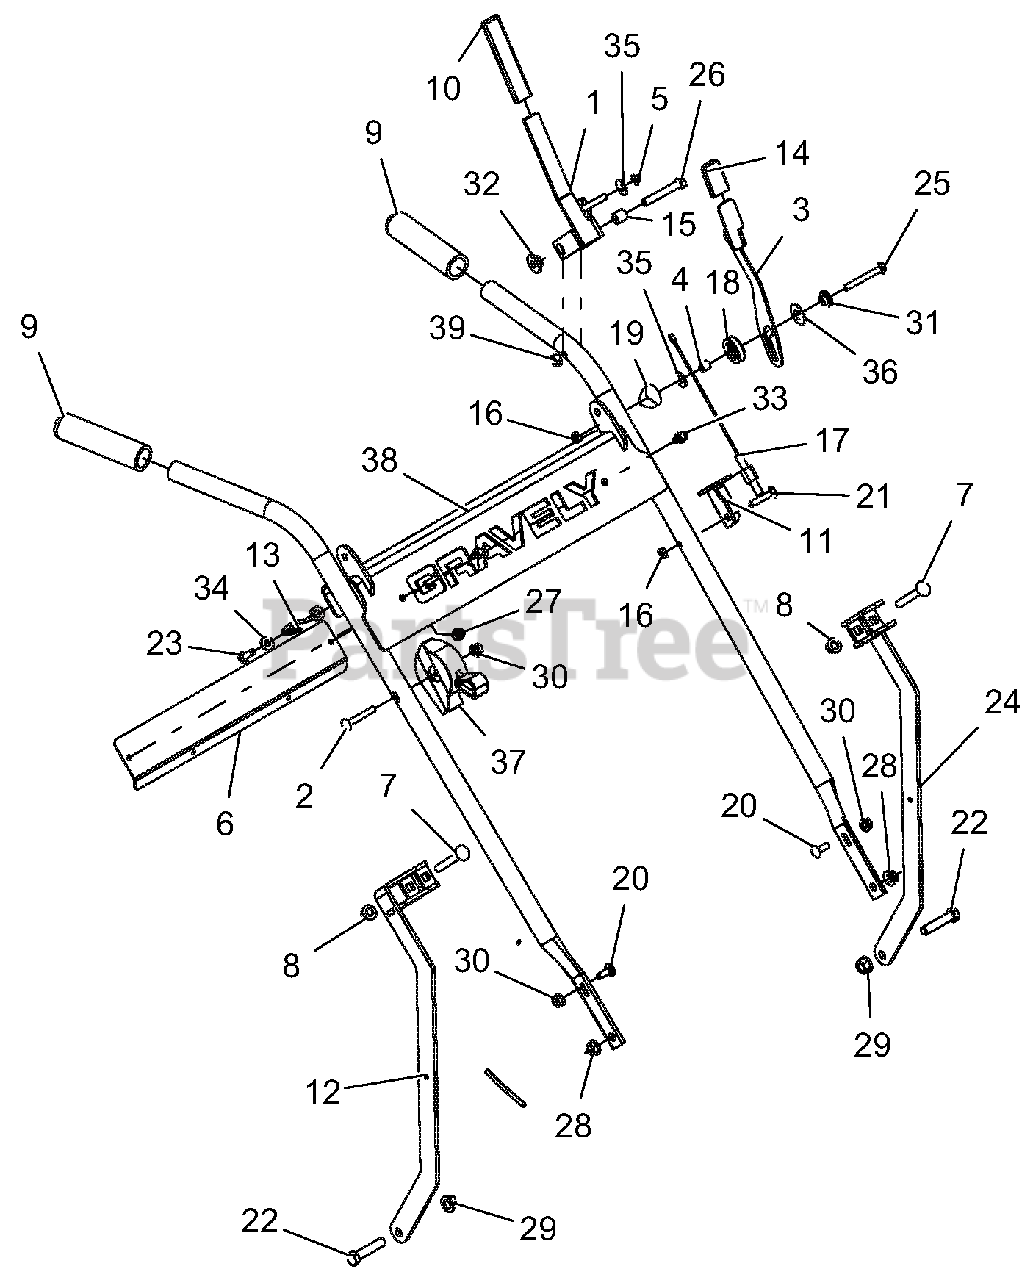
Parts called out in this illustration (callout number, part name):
1	WLDMT, PTO LEVER, HWM (BLACK)
2	BLT-RDHDSQNK .25-20X1.75 G5 Y
3	WLDMT, HWM PTO INTERLOCK
4	TUBE, SPCR .280 X .375 X .375 REV
5	PUSH, NUT .25
6	BACKER, GRAVELY
7	BLT-RDHDSQNK .31-18X2.25 G5 Y
8	NUT-LK-NYL-FLG .31-18 YWZC
9	GRIP, BLACK 7/8ID
10	GRIP, MZR/MOMENT SP 7/8X3/4X4
11	MOUNT, UPPER PTO CABLE (BLACK)
12	WLDMT, RH HANDLEBAR SUPPORT (RED)
13	GUIDE, PULLCORD
14	GRIP, THUMB LATCH
15	BSHG-SLV .334X.500X.50
16	NUT-JAM-NYL .250-20 W/INSERTYZ
17	CABLE, WAW PTO
18	PULLEY, CABLE
19	SPCR, HANDLEBAR
20	BLT-RDHDSQNK .25-20X.75 G5 YWZC
21	BLT-RDHDSQNK .25-20X1.25 G5 Y
22	BLT-HEX .38-16X1.75 GR5 YWZC
23	BLT-HEX .25-20X.75 GR5 YWZC
24	WLDMT, LH HANDLEBAR SUPPORT (RED)
25	BLT-HEX .25-20X2.00 GR5 YWZC
26	BLT-HEX .31-18X2.00 GR5 YWZC
27	NUT-LK-NYL .250-20 YWZC
28	NUT, LK-TOP-FLG .312-18 YWZC
29	NUT, LK-TOP-FLG .38-16 YWZC
30	NUT, LK-TOP-FLG .25-20 YWZC
31	BSHG, FLG .266X.42X.150 PM
32	BSHG, FLG .32X.500.344X.880
33	SCR-TAP .25-20X.50 HWH TR YWZ
34	WSHR-FL-STL.281X.62X.065 YWZC
35	WSHR-FL-STL.312X.734X.065 YWZ
36	WSHR-FL-STL.438X1.00X.083 YWZC
37	CABLE, THROTTLE , KILL & CHOKE
38	WLDMT, HANDLEBAR HW MOWER (RED)
39	NUT-LK-CTR .31-18 YWZC
